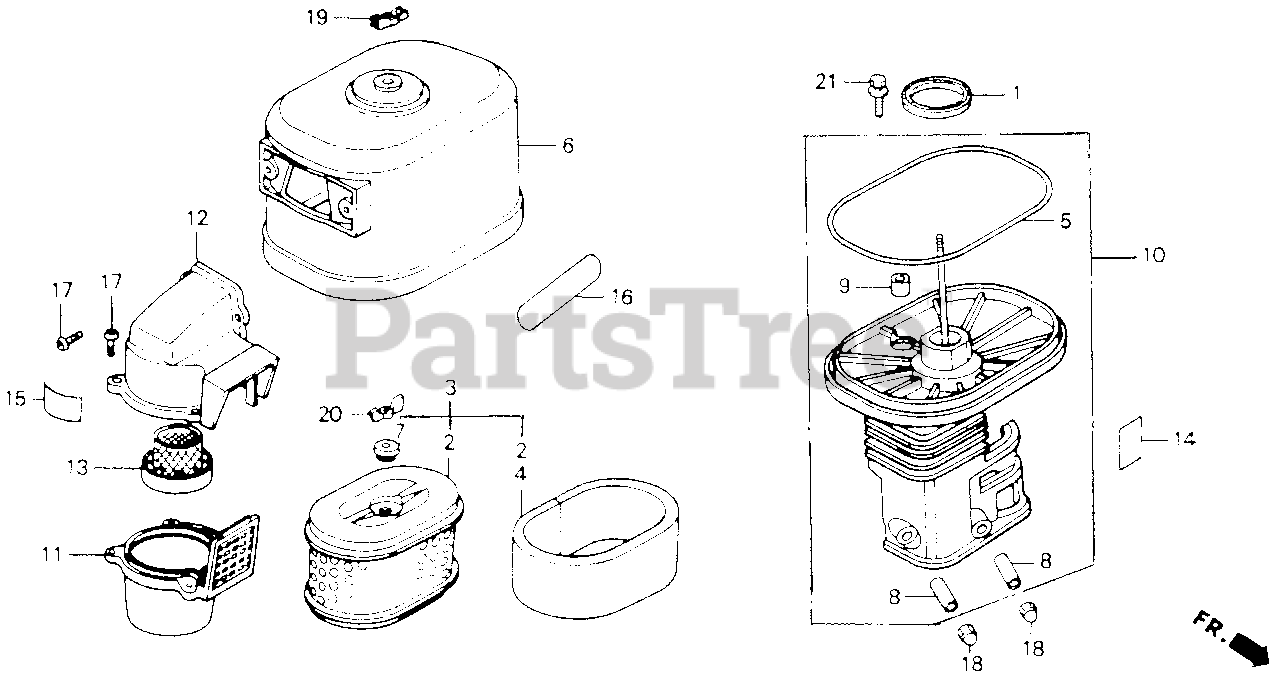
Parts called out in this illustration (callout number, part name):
1	GASKET, ELBOW
2	ELEMENT, AIR CLEANER
3	ELEMENT, AIR CLEANER
4	FILTER (OUTER)
5	SEAL, AIR CLEANER COVER
6	COVER, AIR CLEANER (CYCLONE)
7	GROMMET, AIR CLEANER
8	COLLAR, AIR CLEANER
9	COLLAR B, AIR CLEANER
10	ELBOW, AIR CLEANER
11	CASE, PRE AIR CLEANER
12	CAP, PRE AIR CLEANER
13	GUIDE, PRE AIR CLEANER
14	MARK, CHOKE (EXTERNAL)
15	LABEL, AIR CLEANER CAUTION
16	MARK, AIR CLEANER SALES POINT
17	SCREW, PAN (5X16.5)
18	NUT, CAP (6MM)
19	WINGNUT, AIR CLEANER COVER
20	WINGNUT, TOOL BOX SETTING
21	BOLT-WASHER (6X20)
